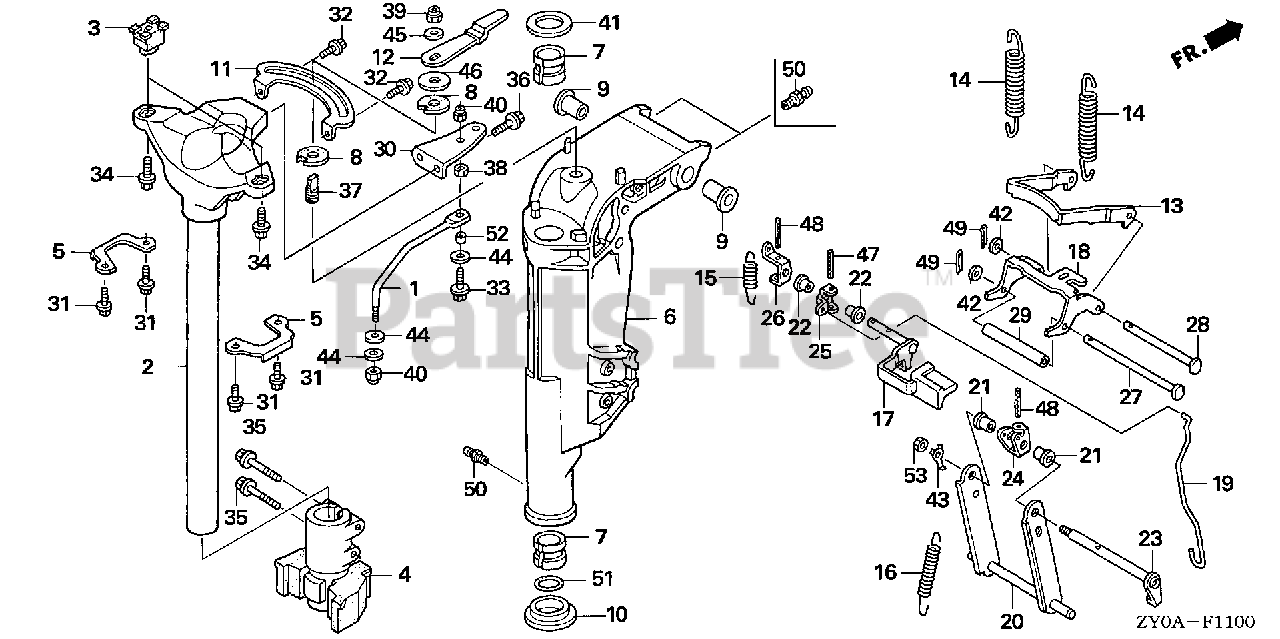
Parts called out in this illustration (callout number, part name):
2	FRAME, MOUNTING (S)
3	RUBBER, MOUNTING (UPPER)
4	RUBBER, MOUNTING (LOWER)
5	COVER, MOUNTING RUBBER (UPPER)
6	CASE, SWIVEL *NH282MU* (S) (OYSTER SILVER METALLIC-U)
7	LINER, SWIVEL CASE
8	BLOCK, FRICTION
9	BUSH, SWIVEL CASE
10	COLLAR, SWIVEL CASE
11	PLATE, FRICTION
12	LEVER, FRICTION
13	HOOK, REVERSE LOCK
14	SPRING, REVERSE LOCK
15	SPRING, TILT LEVER
16	SPRING, TILT LINK
17	LEVER, TILT
18	ARM, REVERSE LOCK
19	ROD, RELEASE SWIVEL CASE
21	BUSH, TILT LEVER
22	BUSH, TILT LEVER
23	SHAFT, TILT
24	BRACKET, TILT SHAFT
25	BRACKET, RELEASE ROD
26	BRACKET, TILT LEVER
27	SHAFT, REVERSE LOCK (A)
28	SHAFT, REVERSE LOCK (B)
29	COLLAR, REVERSE LOCK
31	BOLT, FLANGE (6X12)
32	BOLT, FLANGE (6X12)
34	BOLT, FLANGE (10X25)
35	BOLT, FLANGE (8X45)
37	BOLT, STUD (8X26)
39	NUT, SELF-LOCK (8MM)
41	WASHER, THRUST
42	WASHER, PLAIN (6MM)
43	WASHER, LOCK
45	WASHER (8MM)
46	WASHER, NYLON (8MM)
47	PIN, SPRING (3.0X22)
48	PIN, SPRING (3.0X25)
49	PIN, SPLIT (2.0)
50	NIPPLE, GREASE
51	O-RING (34X2.4)
53	NUT, HEX. (6MM)
